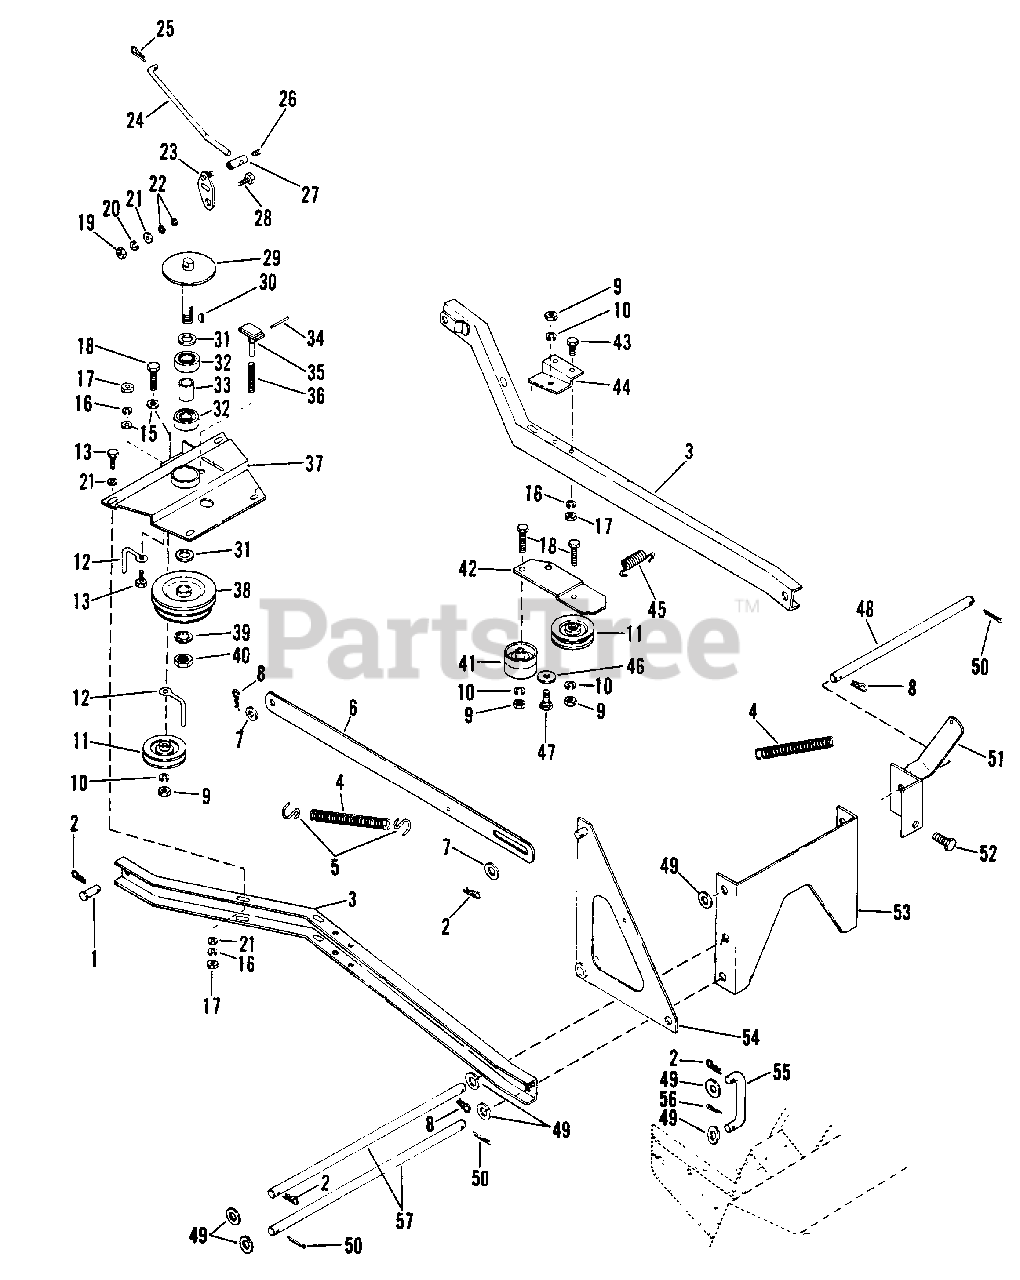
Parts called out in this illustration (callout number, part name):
1	Pin, Clevis
2	Hairpin, Internal
3	Channel
4	Spring, Ext. 9-15/16 Free Length
5	Hook, ÒS"
6	Strap, Lift
7	Washer, Flat .500x1.250x.083
8	Pin, Hair
9	Nut, Hex 3/8-16
10	Washer, Lock 3/8 Reg.
11	Idler .375x3.06
12	Finger, Belt
13	Bolt, Hex 5/16-18x1.00
15	Washer, Flat .406x.812x.065
16	Washer, Lock 5/16 SP
17	Nut, Hex 5/16-18
18	Bolt, Hex 3/8-16x1.75
19	Nut, Hex 1/4-20
20	Washer, Lock
21	Washer, .312x.734x.065
22	Washer, Flat .250x.500x.049
23	Actuator, Brake
24	Rod, Brake
25	Pin, Hair Int. 3/32
26	Set Screw, 5/16-18x.375 HSCP
27	Adaptor, Rod
28	Bolt, Hex 1/4-20x.750
29	Shaft, Spindle
30	Key, Woodruff .187x.75x#9
31	Washer, Flat .813x2.0x.148
32	Bearing, Radial
33	Spacer
34	Pin, Spring .187x1.75
35	Plunger, Brake
36	Spring, Comp.
37	Housing, Spindle
38	Sheave, Double
39	Lockwasher, Internal 3/4
40	Nut, Jam 3/4-10 Hex
41	Idler, .375x2.25
42	Arm, Idler
43	Bolt, Hex 5/16-18x.75
44	Mount, Idler
45	Spring, Ext. 3-1/16 Free Length
46	Washer, Flat .515x1.441x.1
47	Bolt, Shoulder
48	Rod, Mount
49	Washer, .656x1.312x.095
50	Pin, Cotter .156x1.50
51	Anchor, Spring
52	Bolt, Hex 1/2-13x1.25
53	Support, Pivot
54	Bellcrank, Lift
55	Link, Lift
56	Pin, Cotter .125x1.00
57	Rod, Pivot
